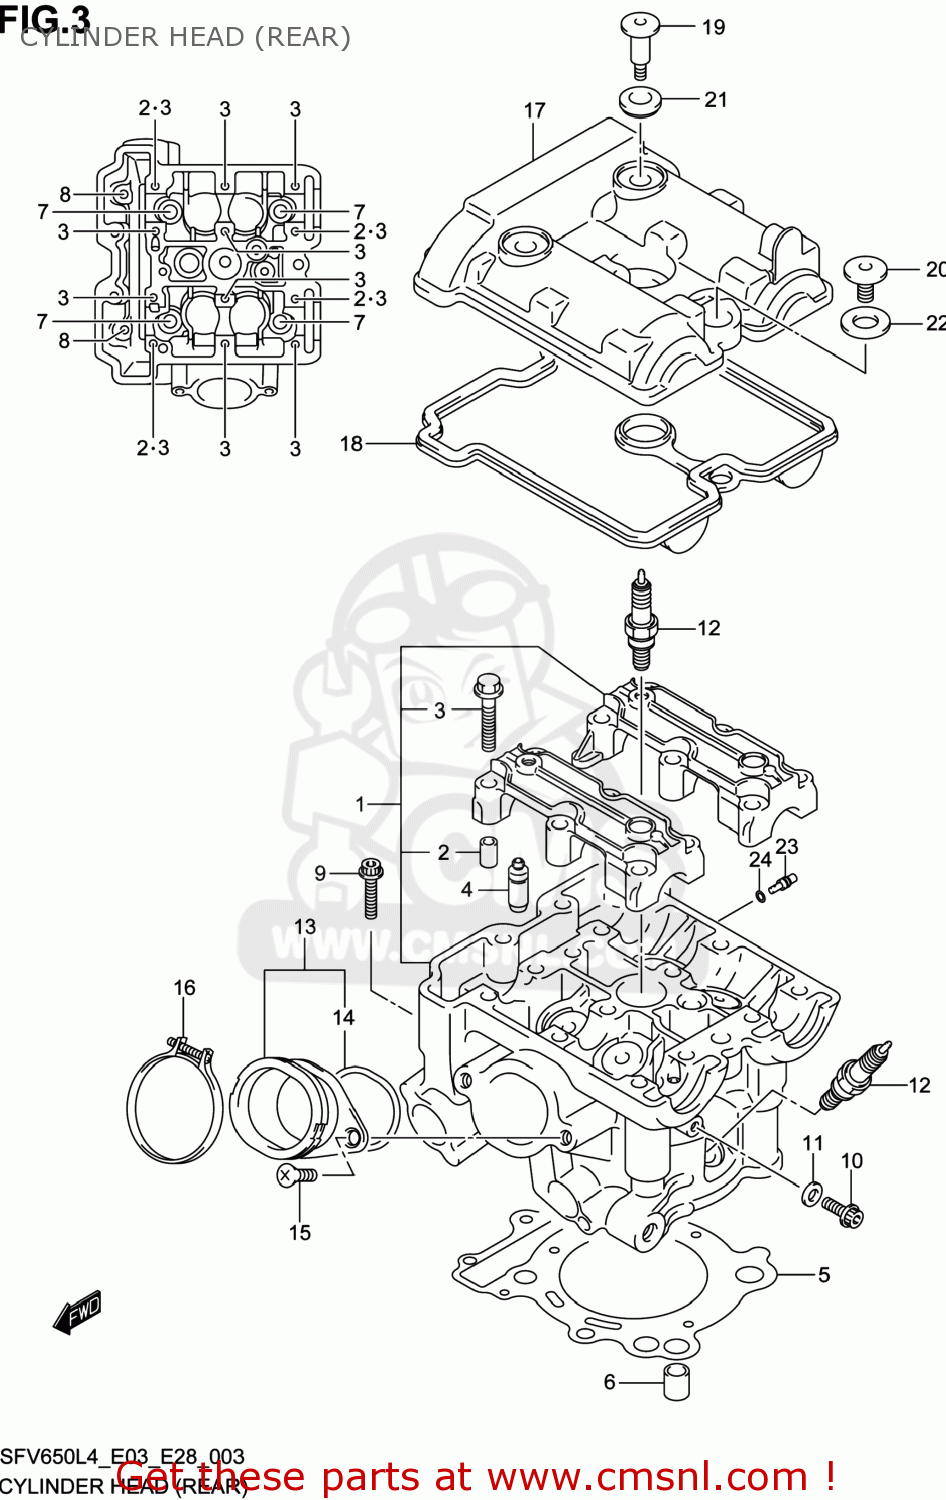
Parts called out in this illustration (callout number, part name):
1	HEAD ASSY,CYLINDER RR
2	PIN(6.2X8X11)
3	BOLT(6X40)
4	GUIDE,VALVE
5	GASKET,CYLINDER HEAD (NAS)
6	PIN
7	BOLT,CYLINDER HEAD(L:160)
8	BOLT(6X70)
9	BOLT
10	BOLT(6X12)
11	GASKET(5.8X13X1.2) (NAS)
12	PLUG,SPARK(IU24D)
13	PIPE ASSY,INTAKE RR
14	O RING(D:2.4,ID:47X42)
15	SCREW
16	CLAMP,INTAKE PIPE
17	COVER,CYLINDER HEAD RR
18	GASKET,CYLINDER HEAD COVER (NAS)
19	BOLT(7X17.5)
20	BOLT(7X31)
21	WASHER,CYL HEAD COVER
22	CUSHION,HEAD COVER BOLT
23	JET(8)
24	O RING(D:1.2,ID:4)
